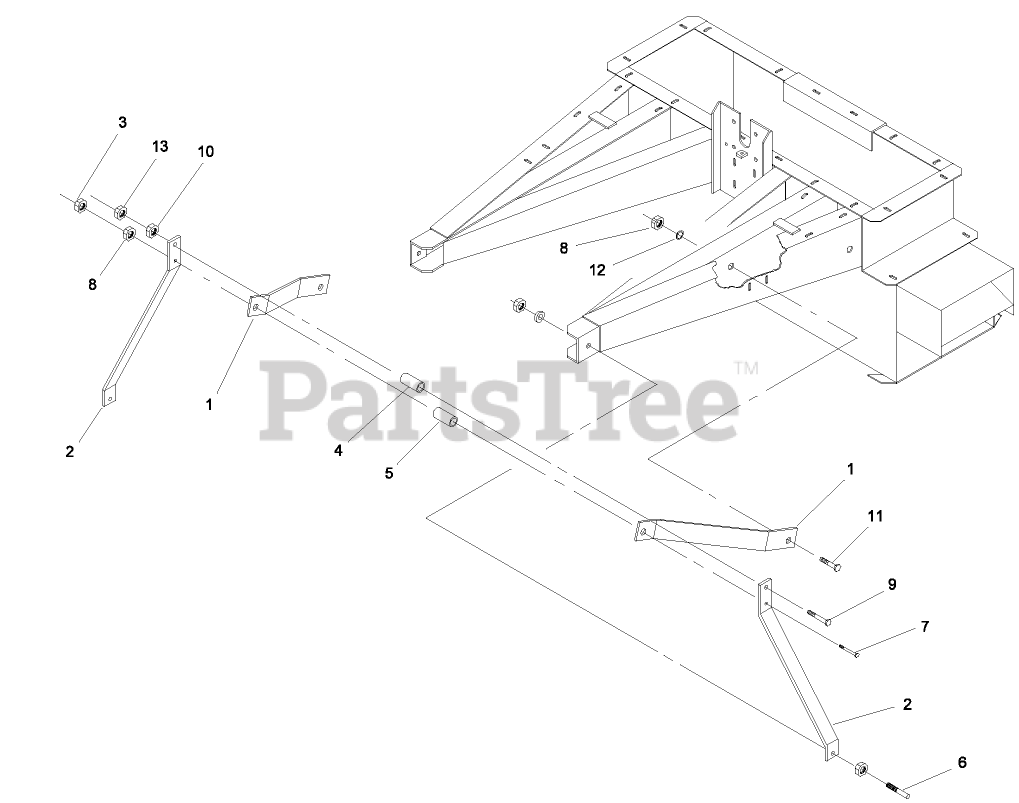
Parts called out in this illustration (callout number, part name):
1	3 PT HITCH BRACE
2	ARM-MOUNT
3	NUT-JAM
4	SPACER-3 PT HITCH, TOP
5	SPACER-3 PT HITCH, BOTTOM
6	LIFT ARM PIN ADJUSTMENT ASM
7	SCREW-HH
8	NUT-HH
9	SCREW-HH
10	NUT-HEX
11	SCREW-HH
12	WASHER-LOCK
13	NUT-JAM
